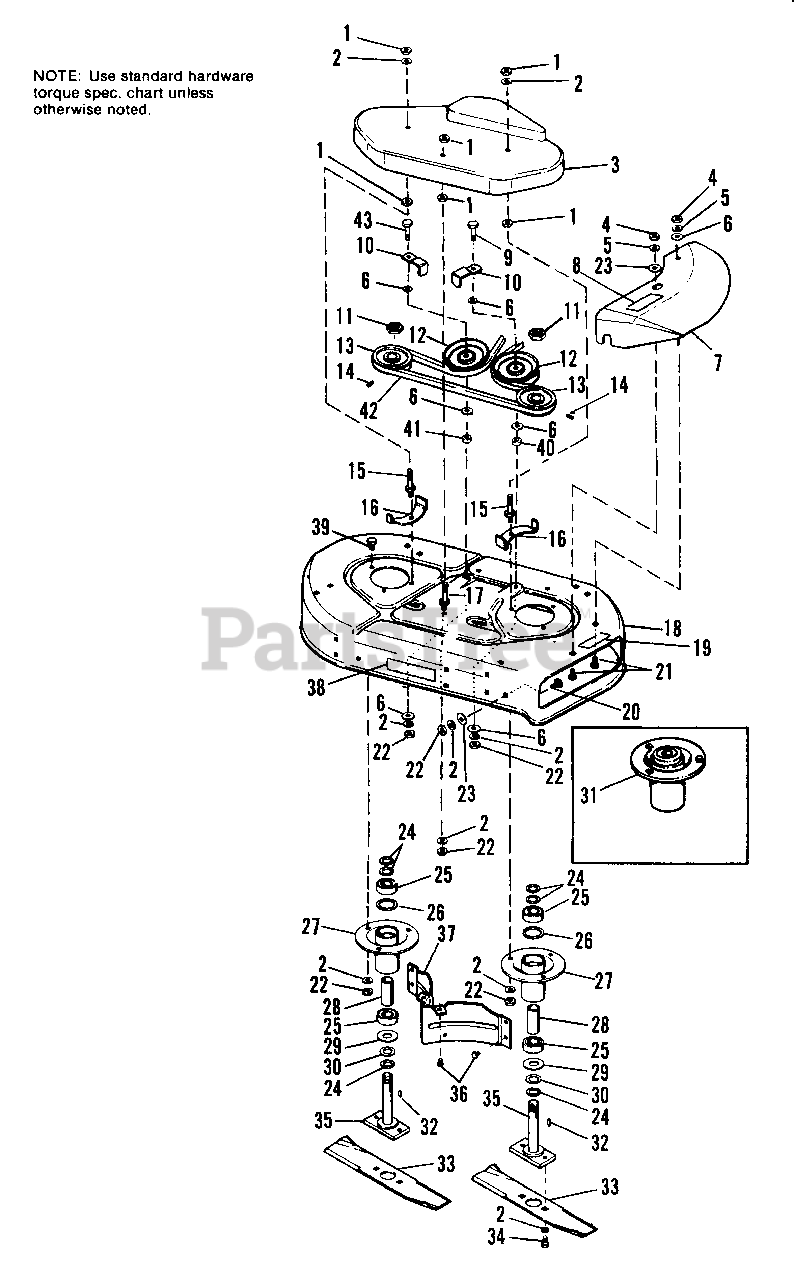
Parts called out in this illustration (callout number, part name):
1	LOCKNUT, Hex, 3/8-16
2	LOCKWASHER, 3/8
3	COVER, Housing
4	NUT, Hex, Full, 5/16-18
5	LOCKWASHER, 5/16
6	WASHER, Plain, 5/16
7	DEFLECTOR
8	DECAL, Safety
9	CAPSCREW, Hex Hd., 3/8-16 x 2
10	GUIDE, Belt
11	LOCKNUT, Jam, 3/4-16
12	PULLEY, Idler
14	SETSCREW, 5/16-18 x 3/8
16	GUIDE, Belt
18	HOUSING, Mower
19	FILM, Safety
20	BOLT, Carriage, 3/8-16 x 3/4
21	BOLT, Carriage, 5/16-18 x 3/4
22	NUT, Hex, Full, 3/8-16
23	WASHER, Special
25	BEARING, Roller
26	RING, Backing
27	TUBE ASSY., Arbor
31	TUBE ASSY., Arbor W/Bearings
32	KEY, Woodruff, #61
33	BLADE, Knife
34	CAPSCREW, Hex Hd., 3/8-16 x 5/8
35	ARBOR ASSY.
36	SCREW, Hex, Self Tapping, 1/4-20 x 3/8
38	DECAL, Simplicity
39	CAPSCREW, Hex Hd., 3/8-16 x 3/4
42	BELT, V, Drive
43	CAPSCREW, Hex Hd., 3/8-16 x 1-3/4
